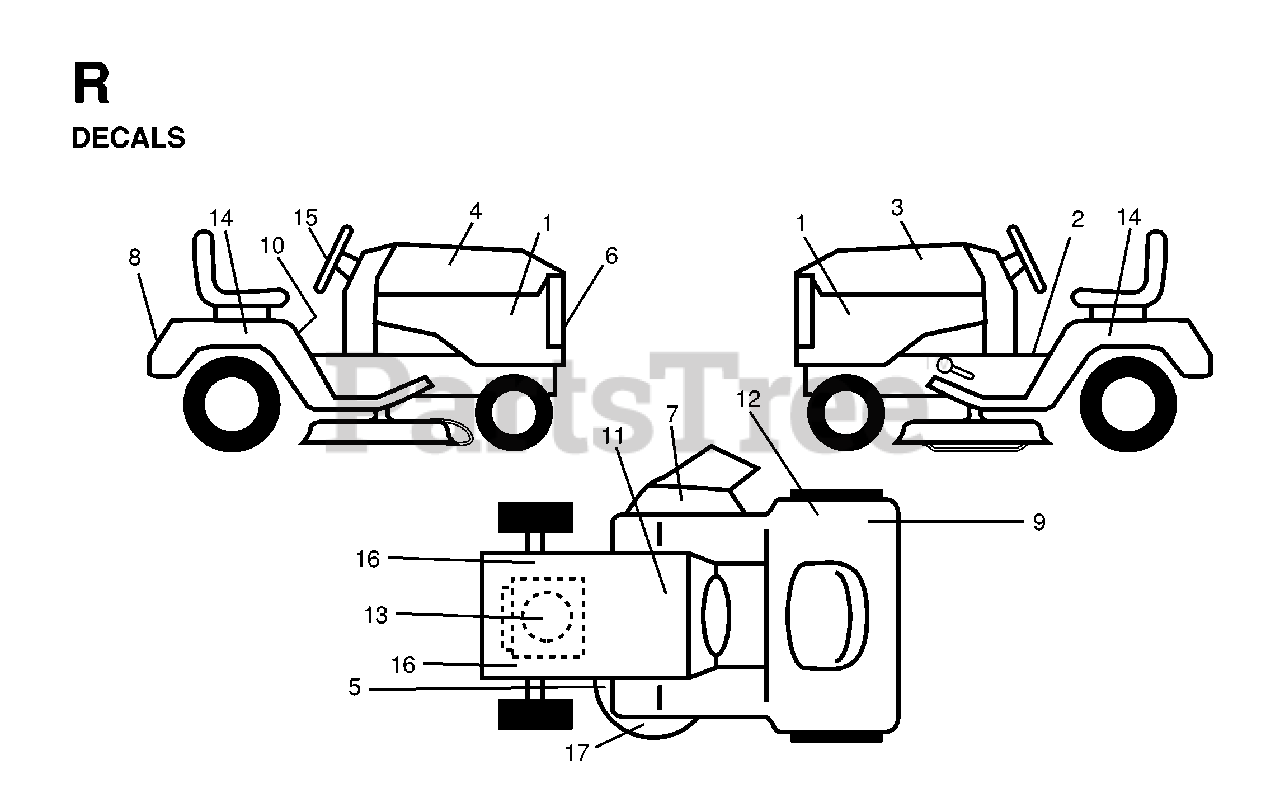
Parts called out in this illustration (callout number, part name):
2	DECAL PARK BRAKE
5	DECAL V BELT SCHEMATIC
7	DECAL MOWER CUT/FINGER
9	DECAL CERTIFICATION
10	DECAL READ OWNER'S MAN SYMS
11	DECAL BTRY SYMBOLS
12	DECAL EUROPE STANDARD CE
13	DECAL HP ENGINE
